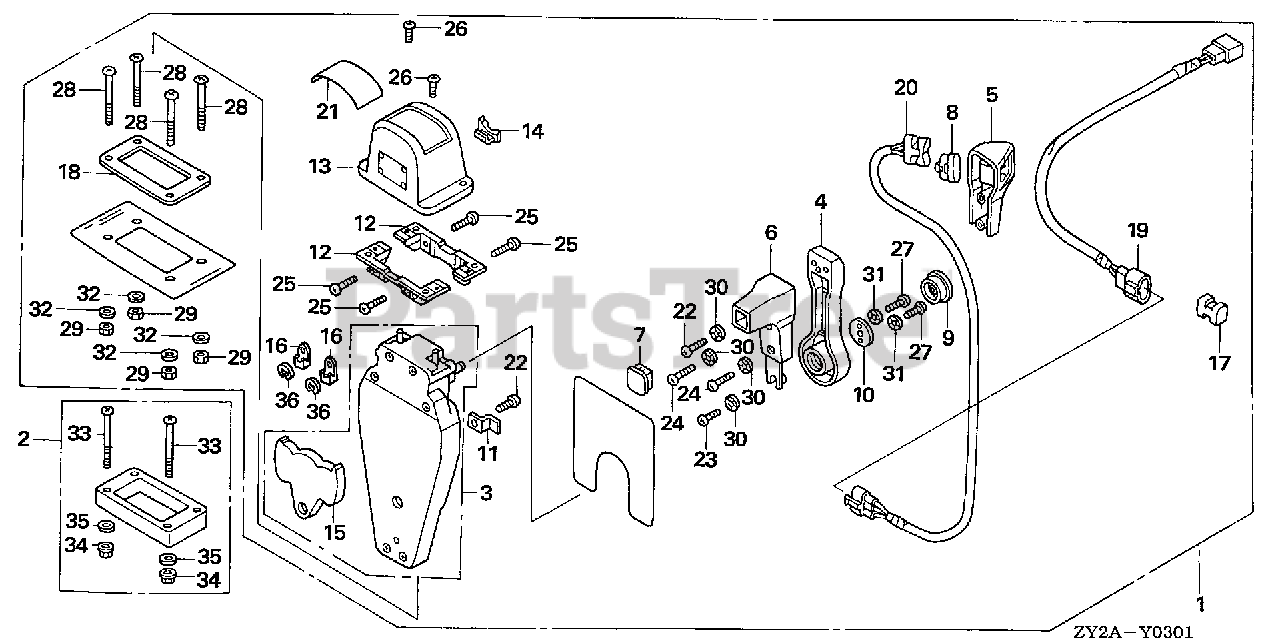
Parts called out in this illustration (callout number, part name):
1	BOX KIT, REMOTE CONTROL (TOP MOUNT SINGLE)(L)
2	SPACER KIT, REMOTE CONTROL BOX (TOP MOUNT SINGLE)
3	HOUSING ASSY., R. (INNER) (TOP MOUNT)
4	HANDLE, REMOTE CONTROL
5	COVER, R. GRIP
6	GRIP, REMOTE CONTROL HANDLE
7	CAP, GRIP
8	CAP, SWITCH
9	BUTTON, THROTTLE
10	PLATE, HANDLE
11	PLATE, CABLE CLAMP
12	BRACKET, REMOTE CONTROL HOUSING
13	HOUSING, REMOTE CONTROL BOX
14	HOUSING, LEAD
15	PLATE, DWELL
16	TERMINAL, CABLE
17	SPACER, CABLE CLAMP
18	GASKET, SINGLE
19	SUB-HARNESS ASSY., POWER TRIM-TILT (B)
20	SWITCH ASSY., POWER TRIM-TILT (B)
21	MARK, REMOTE CONTROL (SINGLE)
22	SCREW, PAN (5X16)
23	SCREW, PAN (5X10)
24	SCREW, PAN (5X20)
25	SCREW, PAN (5X18)
26	SCREW, PAN (4X10)
27	SCREW, PAN (6X18)
28	SCREW, PAN (5X40)
29	NUT, HEX. (5MM)
30	WASHER, LOCK (5MM)
31	WASHER, LOCK (6MM)
32	WASHER, PLAIN (5MM)
33	SCREW, PAN (5X65)
34	NUT, HEX. (5MM)
35	WASHER, PLAIN (5MM)
36	E-RING (6MM)
